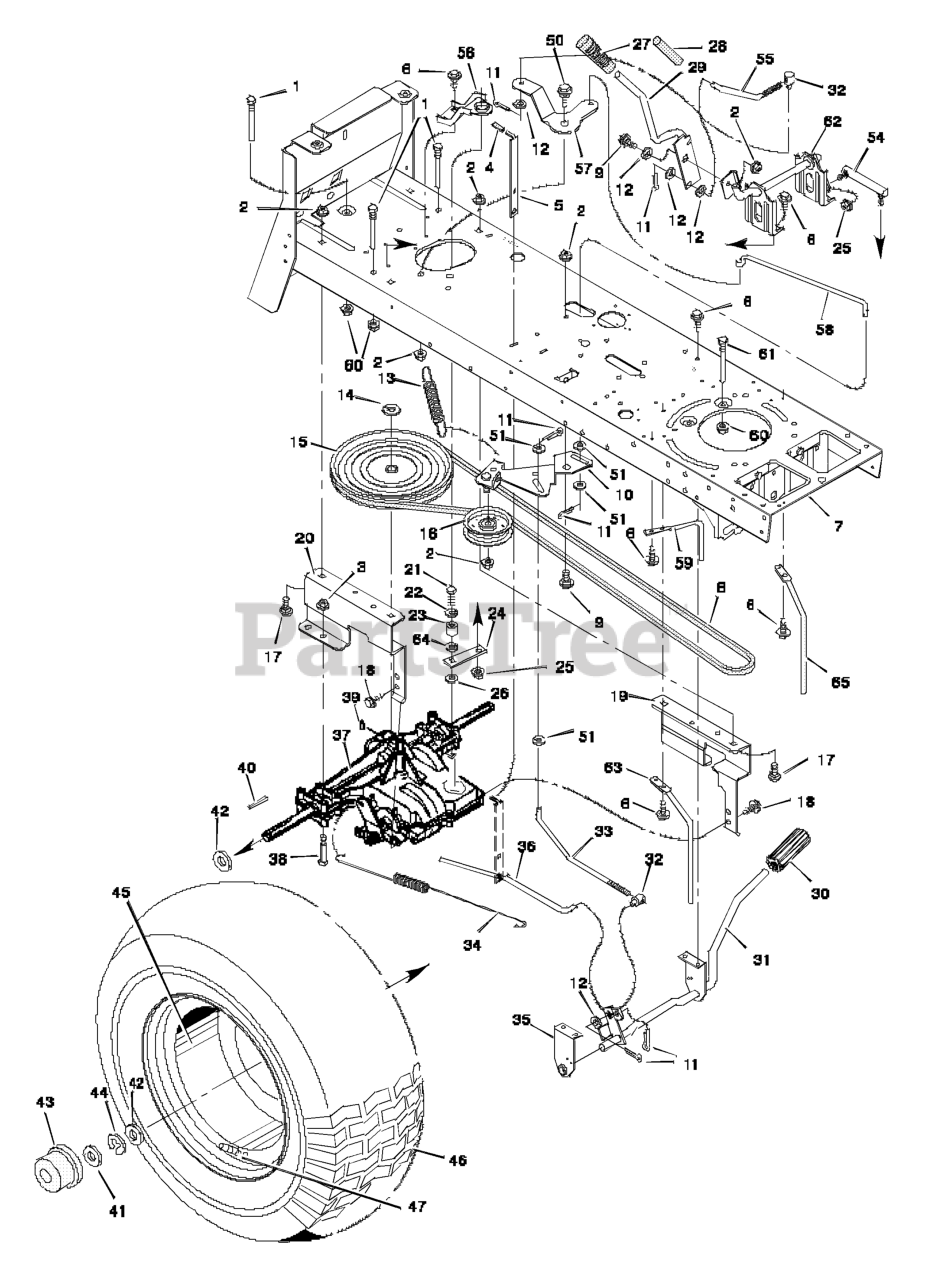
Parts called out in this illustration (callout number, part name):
1	Guide, Belt
2	Locknut, Flange
3	Locknut, Flange
5	Lever, Parking Brake
8	Belt, Motion Drive
9	Bolt, Shoulder
10	Bracket Assembly, Idler
11	Pin, Cotter
12	Washer
13	Spring, Drive Extension
14	Ring, Retainer
15	Pulley, Motion Drive
16	Pulley, Backside Idler
17	Bolt, Carriage
19	Bracket, Left Transaxle
20	Bracket, Right Transaxle
21	Bolt, Hex
22	Lockwasher
23	Pilot, Support
24	Yoke, Shift Lever
25	Locknut
28	Grip, Inner
29	Lever, Shift
30	Pedal, Clutch/Brake
31	Lever Assembly, Pedal
32	Nut, Adjustable
33	Rod, Clutch
34	Spring, Brake Extension
35	Bracket, Pedal Support
36	Rod, Brake Latch
37	Transaxle, Peerless **
38	Bolt, Hex
39	Key, Woodruff No. 9
40	Key, Square
42	WASHER, 1-1.3 16G FLT
43	Hub Cap
45	Wheel & Tire Assembly
46	Tire Only *
47	Valve Stem
50	Bolt, Shoulder
51	Washer
52	Washer
54	Link, Shifter
55	Link, Clutch
56	Bracket, Support
57	Bracket, Pivot
58	Rod, Clutch
59	Guide, Belt
60	Nut, Flange
61	Guide, Belt
62	Shifter Assembly
63	Guide, Belt
64	Washer
65	Guide, Belt
